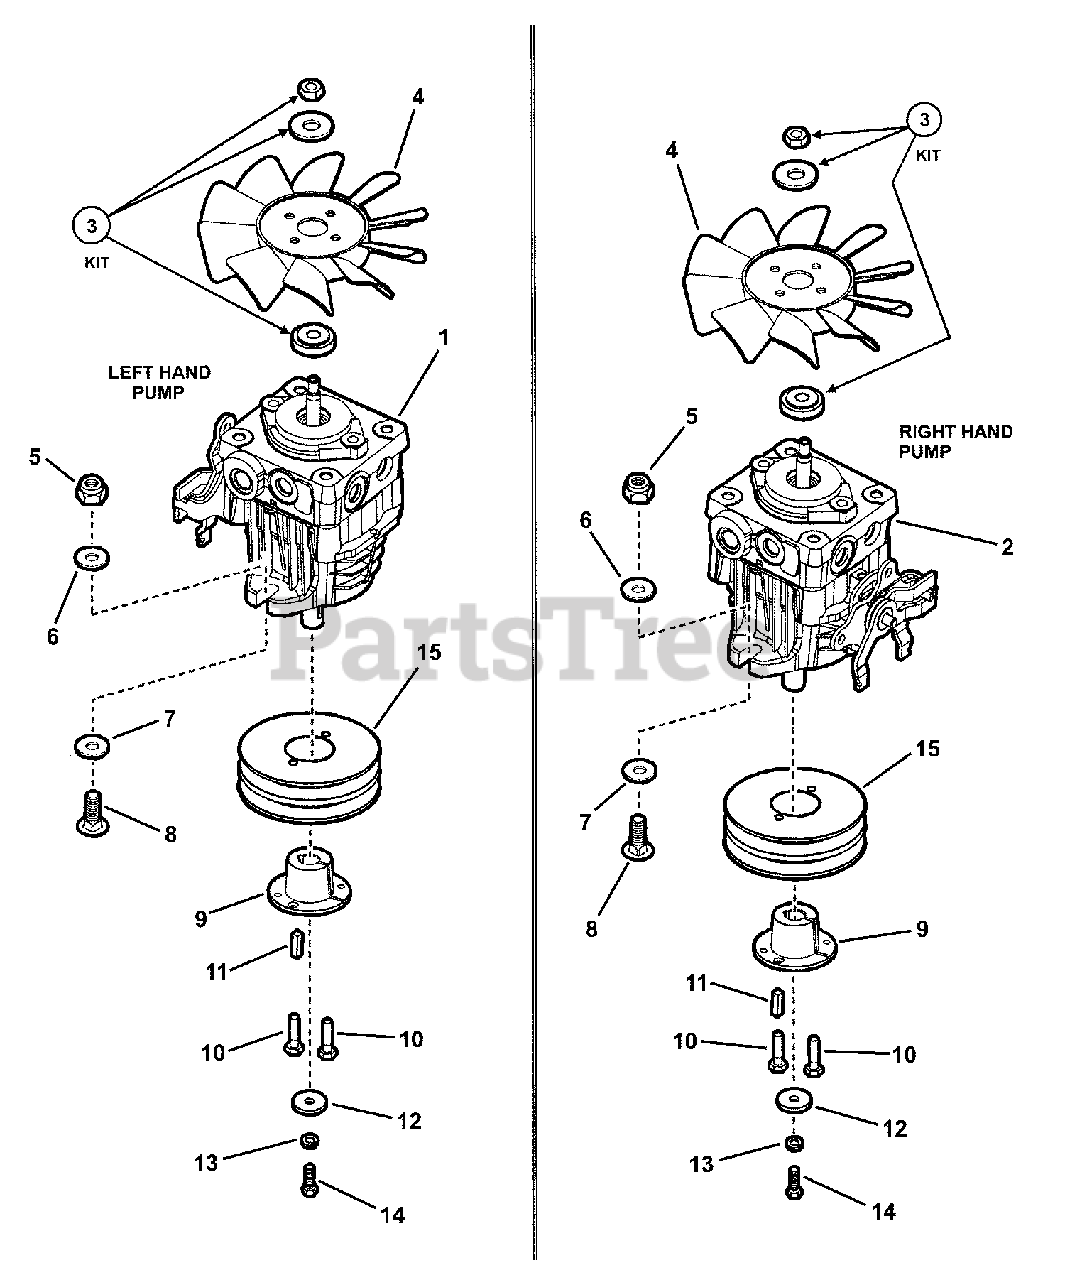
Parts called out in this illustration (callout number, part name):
1	PUMP, Hydro-Gear (BDP-10A-334) Left Hand
2	PUMP, Hydro-Gear (BDP-10A-457) Right Hand
3	HUB KIT for BDP-10A Pump w/Thru Shaft (Incl. 1 ea. of 3 items below)
4	FAN, 7" Nylon, Counter-Clockwise
5	NUT, 3/8-16 HEX NYLON LOCK
6	WASHER, 3/8" Flat
7	RETAINER, 3/8" Bolt
8	BOLT, 3/8-16 x 1-1/4" Short Neck Carriage GR 5
9	PULLEY, "D" Bushing x 15mm Bore
10	SCREW, 1/4-20 x 1" Hex Head Cap, GR 5
11	KEY, M5 x M20
12	WASHER, .281 x 1.00 x .125 Flat
13	WASHER, 1/4" Split Lock
14	SCREW, M6 1.0X12MM, Hex Head, CZ
15	PULLEY, 4.25 O.D. x 1.375 OA x "H" Tapered Bore
